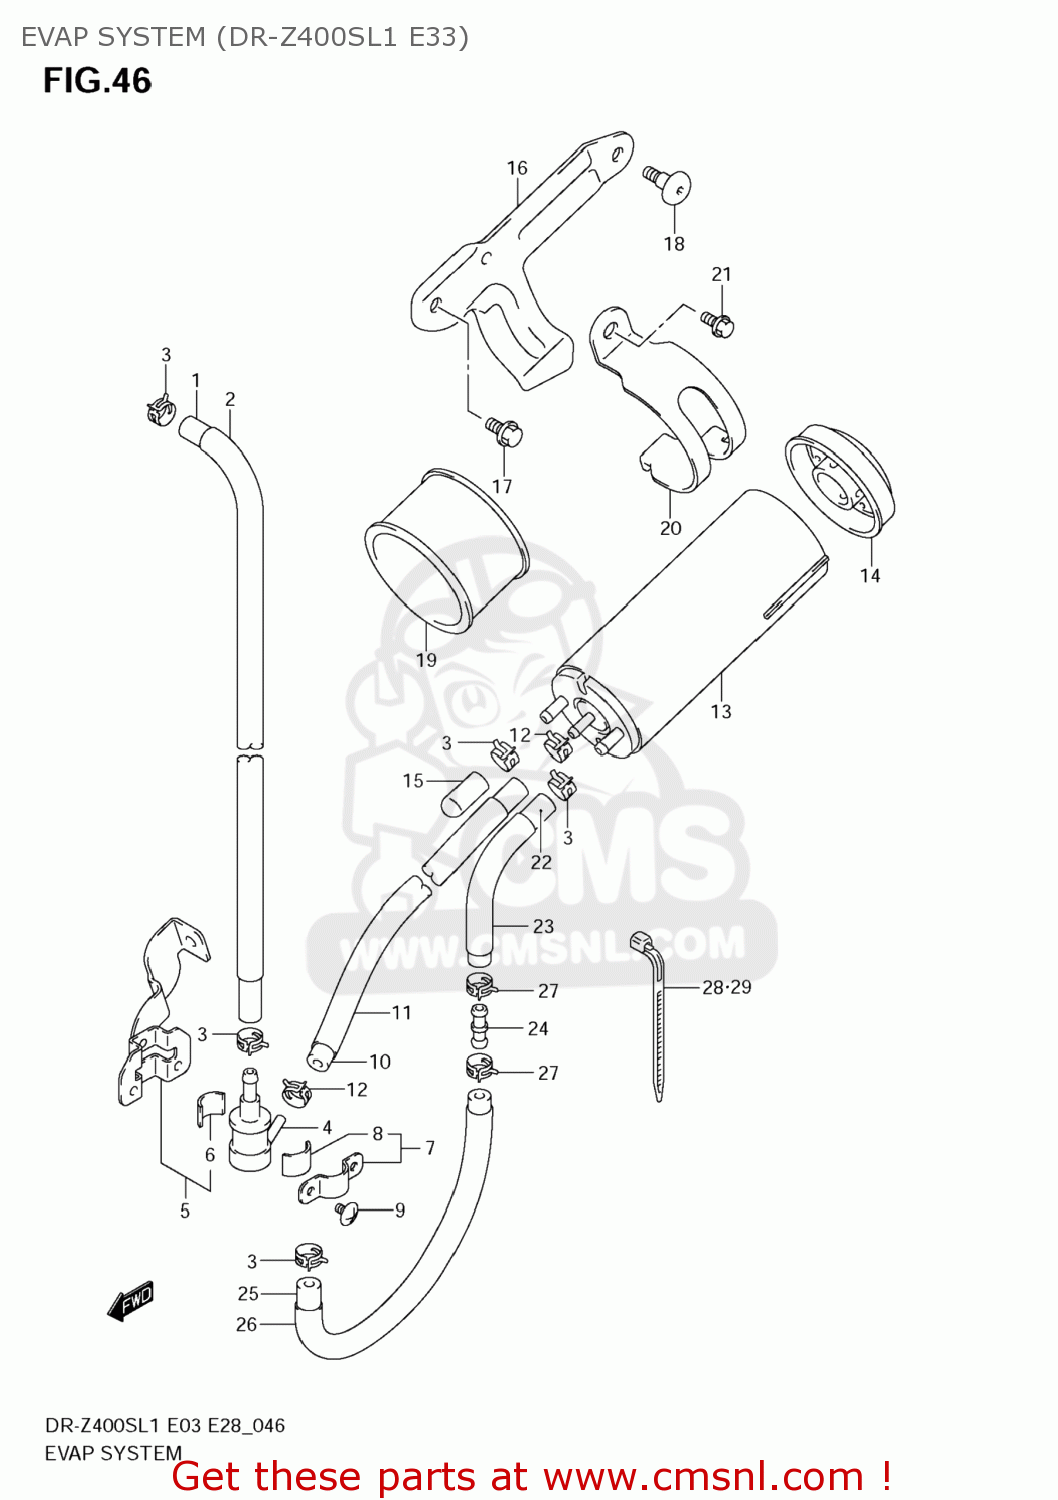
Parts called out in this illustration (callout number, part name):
1	HOSE,TANK & BREATHER VALVE
2	PROTECTOR(14.5X15.5X600)
3	CLIP
4	VALVE,FUEL TANK BREATHER
5	BRACKET,BREATHER VALVE
6	CUSHION
7	PLATE,FUEL TANK BREATHER NO.2
8	CUSHION
9	SCREW
10	HOSE,BREATHER VALVE & CANISTER
11	HOSE
12	CLIP
13	CANISTER ASSY,CHARCOAL
14	CAP,CANISTER
15	CAP,OD:11.5
16	BRACKET,CANISTER
17	BOLT
18	BOLT(6X16)
19	CUSHION,CANISTER
20	HOLDER,CANISTER
21	BOLT
22	HOSE,CSTR PURGE
23	PROTECTOR(14.5X15.5X600)
24	UNION
25	HOSE,CSTR & CARB PURGE NO.2
26	PROTECTOR(14.5X15.5X600)
27	CLIP
28	CLAMP(L:145)
29	CLAMP(L:125)
